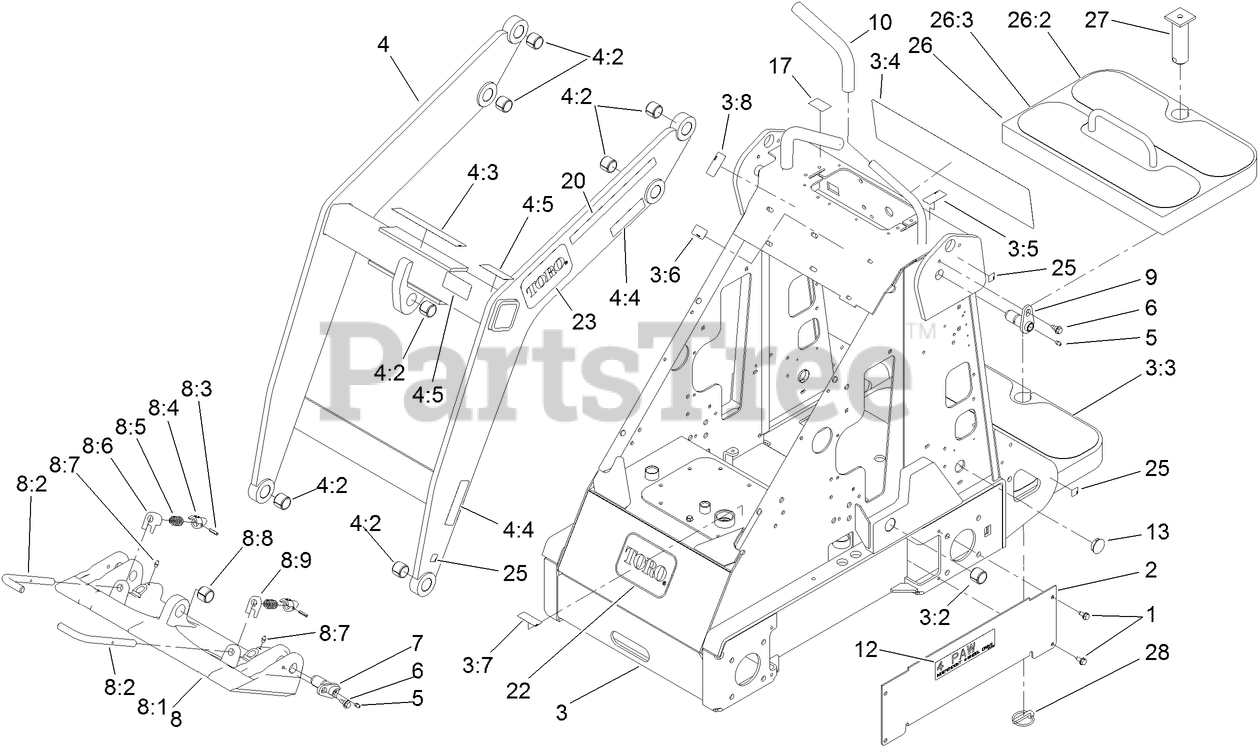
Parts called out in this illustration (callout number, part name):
1	SCREW-HWHTF
2	COVER-HOSE
3	FRAME ASM
3:2	BUSHING-TENSION
3:3	TREAD-FOOT
3:4	DECAL-CONTROL PANEL, CE
3:5	DECAL-THROTTLE
3:6	DECAL-LIMITER, SPEED
3:7	DECAL-OIL, HYD
3:8	DECAL-SELECTOR
4	LOADER ASM
4:2	BUSHING-TENSION
4:3	DECAL-CAUTION
4:4	DECAL-WARNING, PINCH
4:5	DECAL-NO RIDER
5	FITTING-GREASE
6	BOLT-SHOULDER
7	PIN-PIVOT
8	QUICK ATTACH ASM
8:1	MOUNT-QTACH
8:2	PIN-LOCKING
8:3	PIN-GROOVED
8:5	SPRING-COMPRESSION
8:6	STOP-RH
8:7	FITTING-GREASE
8:8	BUSHING-TENSION
8:9	STOP-LH
9	PIN-PIVOT
10	GRIP-CUSHION
13	PLUG-HOLE
17	DECAL-PROTECTION, EAR
22	DECAL
23	DECAL
25	DECAL-POINT, LIFT
26	COUNTERWEIGHT ASM
26:2	TREAD-FOOT
28	PIN-LYNCH
